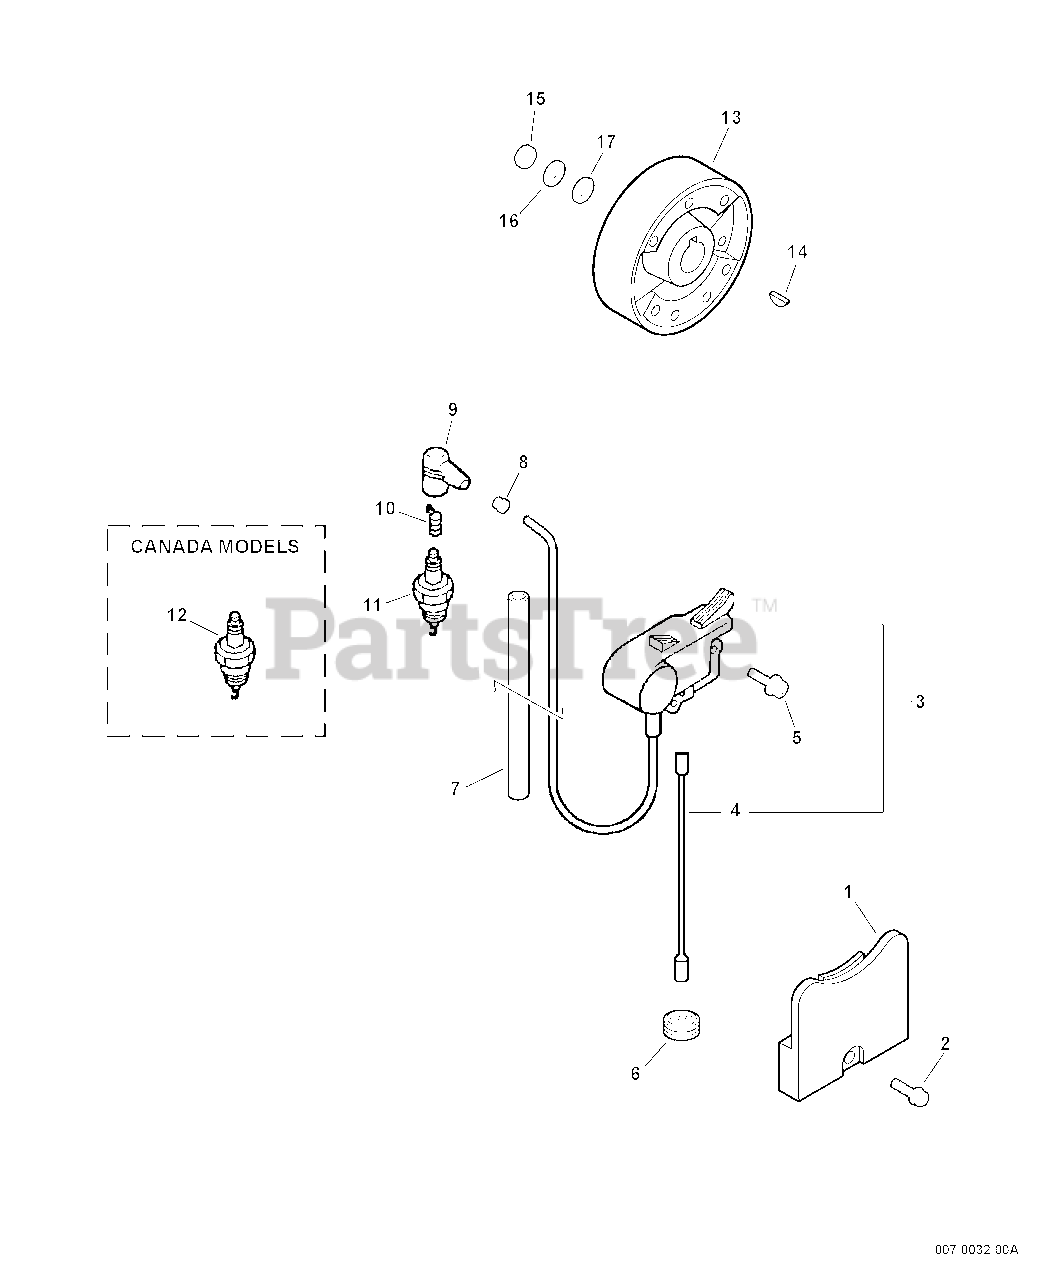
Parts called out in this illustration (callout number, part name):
1	COVER, DUST
2	SCREW 5×18
3	COIL, IGNITION
4	LEAD - GROUND
5	SCREW 5×18
7	TUBE, VINYL 6.3×8×380
8	ADAPTOR, SPARK PLUG - CAP
9	CAP, SPARK PLUG
10	TERMINAL, SPARK PLUG
11	SPARK PLUG - BPM-7Y
12	SPARK PLUG - BPMR7A
13	FLYWHEEL
14	KEY, WOODRUFF 3×14
16	WASHER, SPRING 10
17	WASHER, SPRING 10
